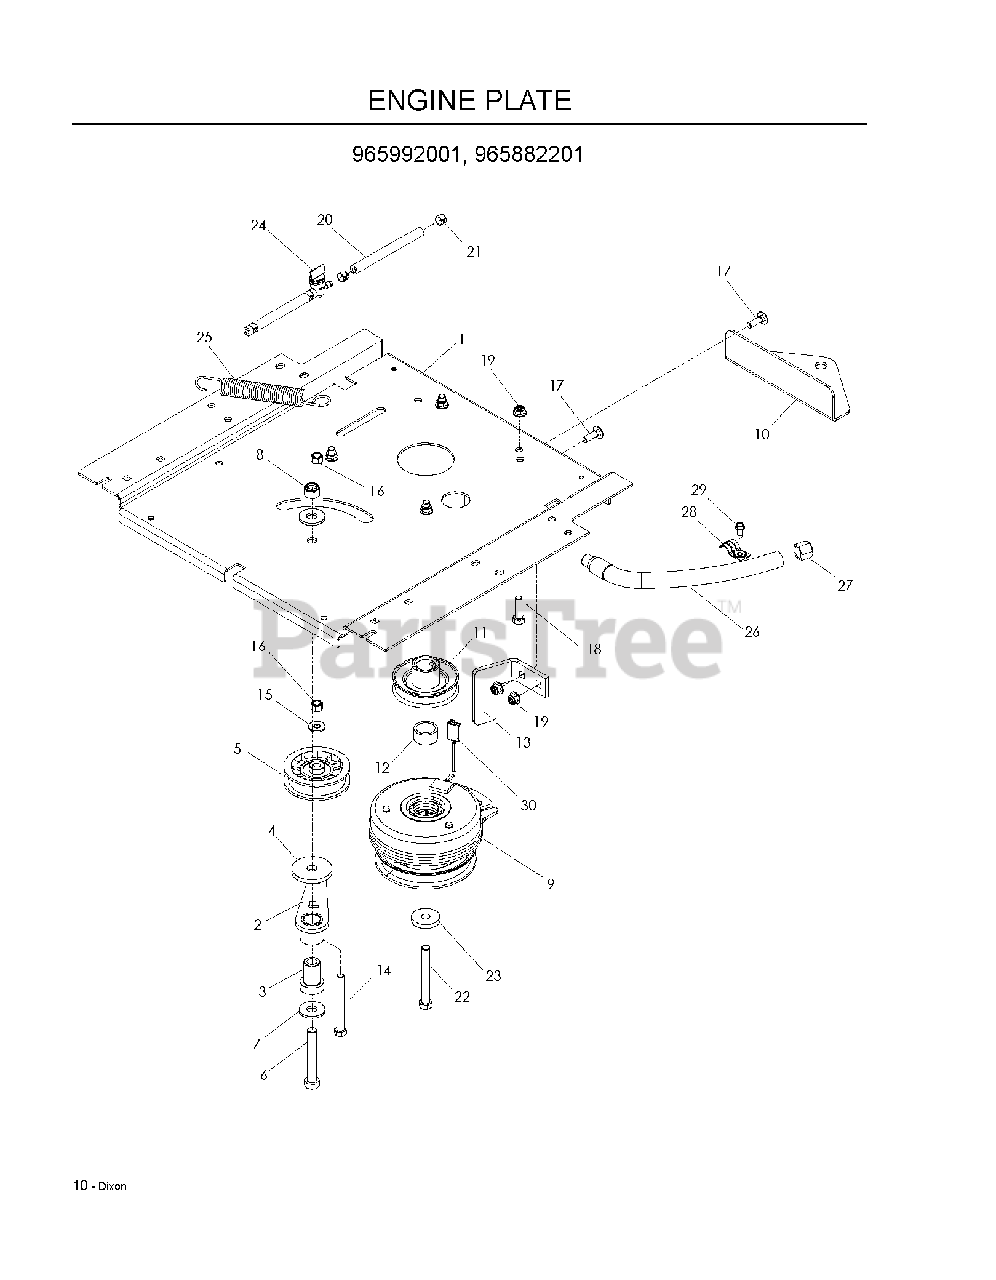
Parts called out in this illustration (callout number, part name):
1	PLATE ENGINE, BLACK
2	IDLER ARM WELDMENT
3	IDLER SPINDLE
4	HEAVY WASHER
5	PULLEY, IDLER
6	HCS 1/2C X 3 1/4
7	WASH USS FLAT 1/2
8	NUT 1/2-13 HEX NYLOC ZD
9	CLUTCH, 105 FT-LBS
10	HITCH, BLACK
11	PULLEY, ENGINE
12	T & B SPACER
13	STOP, CLUTCH, BLACK
14	HCS 3/8-16X3 1/2 GR5
15	WASHER 5/16 FLAT
16	NUT 3/8-16 NYLOC
17	RHSNB 5/16C X 1
18	CAPSCREW 5/16 X 1/1/2 HEX HEAD
19	5/16-18 NYLOC FLANGE NUT
20	FUEL LINE 5"
21	HOSE CLAMP
22	HCS 7/16-20X3-1/2 GR 5 ZN
23	CLUTCH, WASHER
24	FUEL VALVE
25	SPRING, DECK DRIVE
26	OIL DRAIN HOSE
27	DRAIN CAP
29	SCREW 1/4 X 5/8
30	CLUTCH HARNESS
